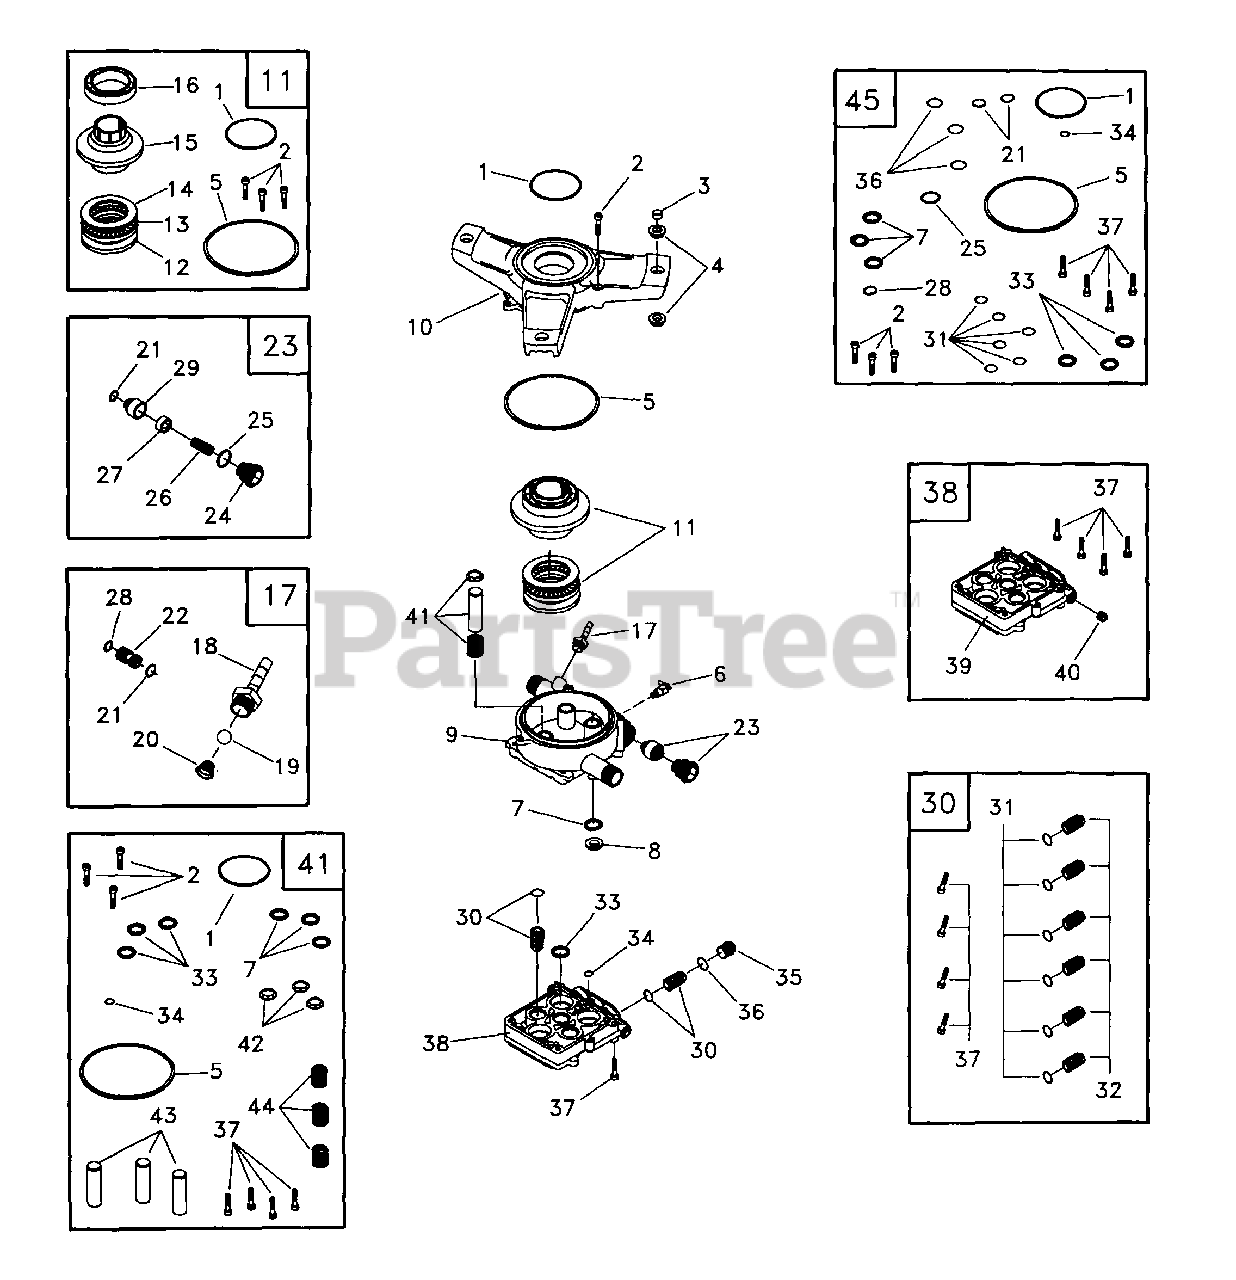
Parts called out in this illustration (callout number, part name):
1	SEAL, Engine Donut
2	SHCS, M6-1 x 25
2	SHCS, M6 - 1 x 25
3	SLEEVE, Grommet Spacer
4	BUSHING, Rubber Mount
5	O-RING, Housing Seal
6	THERMAL RELIEF, GPW-EG
7	SEAL, Oil Piston 15 TC4
8	SPACER, Pilot
9	HOUSING, Piston
10	ADAPTER, Engine
11	KIT, AXIAL CAM SERV
12	WASHER, Brg. 36 x 65 x 6Thk
13	ASSY., Brg. Cage 45 x 65
14	WASHER, Brg. 45 x 65 x 1
15	CAM, Axial 5.6 VS
16	BALL BEARING, 35 x 72 x 17
17	KIT, CHEM INJECT
18	FITTING, Chem Inject
19	BALL, Chem Inject
20	SPRING, Chem Inject
21	O-RING, Venturi & Seat, Black
22	VENTURI, Chem Inject
23	KIT, UNLOADER
24	CAP, Unloader
25	O-RING, Unloader Cap
26	SPRING, Unloader
27	PISTON ASSY., Unloader
28	O-RING, Venturi, Yellow
29	SEAT, Unloader
30	KIT, CHECK VALVES
31	O-RING, Check Valve
32	ASSY., Check Valve
33	SEAL, Double-Lip
34	O-RING, Hi-Pressure Transfer
34	O-RING, High Pressure Transfer
35	CAP, Outlet Check Valve
36	O-RING, Outlet CV Cap
37	SHCS, M6-1.0 x 35
38	KIT, HEAD CASTING SFG
39	HEAD, Pump
40	PLUG, 1/8-28 W/VIRB
41	KIT, PISTON & SPRING
42	RETAINER, Piston Spring
43	PISTON, Dia. 15 x 65
44	SPRING, Piston Return
45	KIT, O-RING/SEAL SERV
